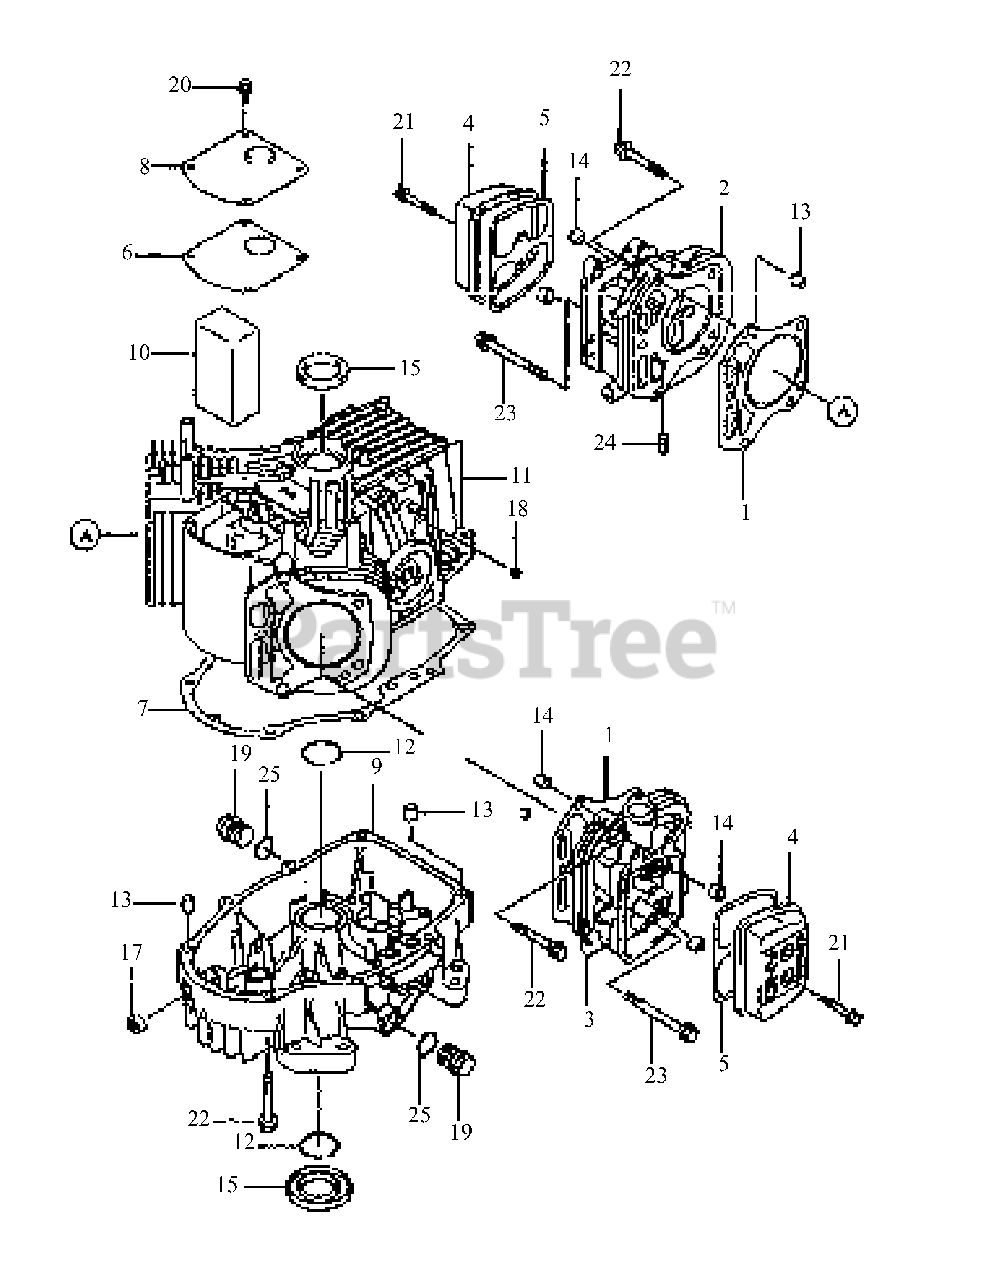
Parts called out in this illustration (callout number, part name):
2	Head, Cylinder #1
3	Head, Cylinder #2
5	Gasket, Rocker Case
6	Gasket, Breather
7	Gasket, Crankcase
8	Cover, Breather
9	Cover, Crankcase
10	Element, Breather
11	Crankcase, Comp
14	Seal, Oil
15	Seal, Oil Crankcase
15	Seal, Oil Cover
19	Plug
20	Bolt, Flange
21	Bolt, Flange
22	Bolt, Flange
23	Bolt, Flange
24	Bolt, Stud
